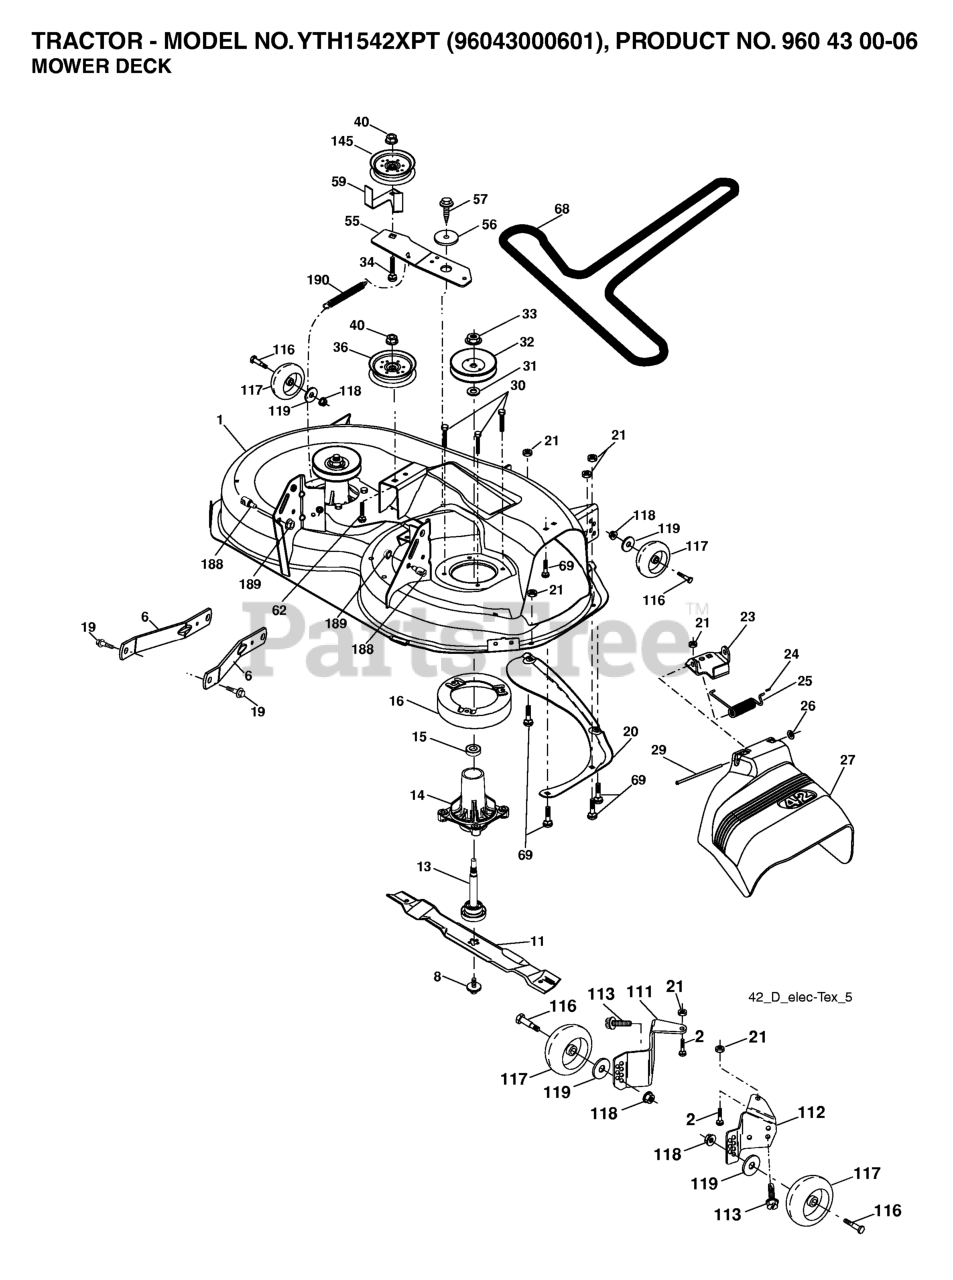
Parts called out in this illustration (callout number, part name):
1	DECK.WELDMENT.42"PAINT
2	RP BOLT 5/16-18 X3/4 ZN/YEL GR
6	ARM.SUSPENSION.MOWER.R
8	BOLT.WASHER.ASM.7/16-2
11	42" HI-LIFT BLADE
13	SHAFT.ASM.MDRL.N/GREASE.38
14	RP.HOUSING.MANDREL.4PT.
16	STRIPPER.MANDREL.ROUND.BLACK
19	BOLT.SHOULDER
20	BAFFLE.VORTEX
21	LOCKNUT
23	BRKT.DEFLECTOR.38"2005+
24	CAP-SLEEVE LT
25	SPRING.TORSION.DEFLECT
26	NUT PUSH M
27	SHIELD.DEFLECTOR.MOWER.42"BLAC
28	Washer 11/32 x 5/8 x 16 Ga SD
29	ROD.HINGE
30	SCREW, WASHER HEAD
31	WASHER.SPACER.MANDREL
32	PULLEY MANDREL
33	NUT.FLANGE.LOCK.TOP
34	BOLT.3/8-16X1.50
36	PULLEY.IDLER.2006
40	NUT LOCK FLG 3/8-16 UNC
45	PULLEY.IDLER.FLAT
55	IDLER.ARM
56	SPACER.RETAINER
57	SCREW 3/8-16X1
59	GUARD, BELT
61	SPRING EXT ELEC CLUTCH
62	BOLT
68	BELT V SECONDARY
69	BOLT
111	BRACKET, WHEEL
112	BRACKET, WHEEL
113	BOLT.5/16HEX.WHS.HD
116	BOLT.SHLD."A"2.41."B"1.66
117	WHEEL.GAGE.HALF.SPOKED
118	NUT LOCK FLG 3/8-16 UNC
119	WASHER
145	PULLEY.IDLER.FLAT.PLATED
188	STUD.FASTNER.W/ANTI-ROTATE
189	NUT LOCK HEX FLANGE 5/16-18
190	SPRING.MOWER.DRIVE.ELECTRIC
